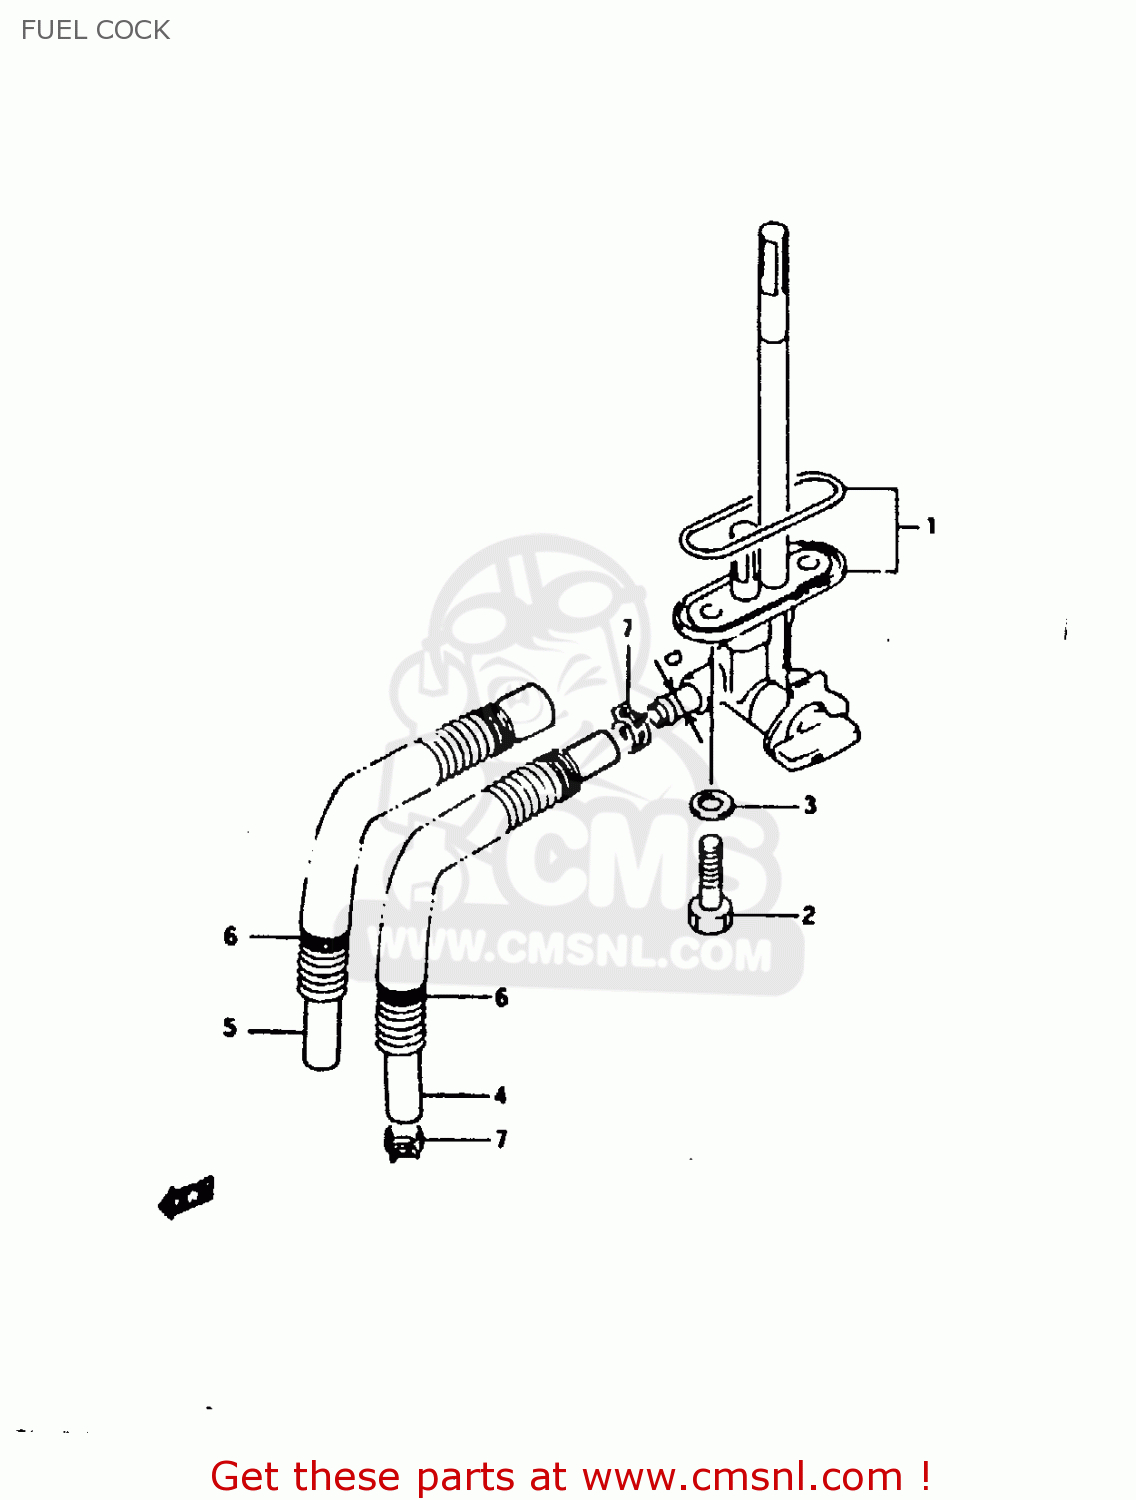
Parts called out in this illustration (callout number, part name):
1	COCK ASSEMBLY,FUEL
2	BOLT(6X20)
3	GASKET(6.4X11.5X0.8) (NAS)
4	HOSE
5	HOSE, FUEL
6	SPRING
7	CLIP
